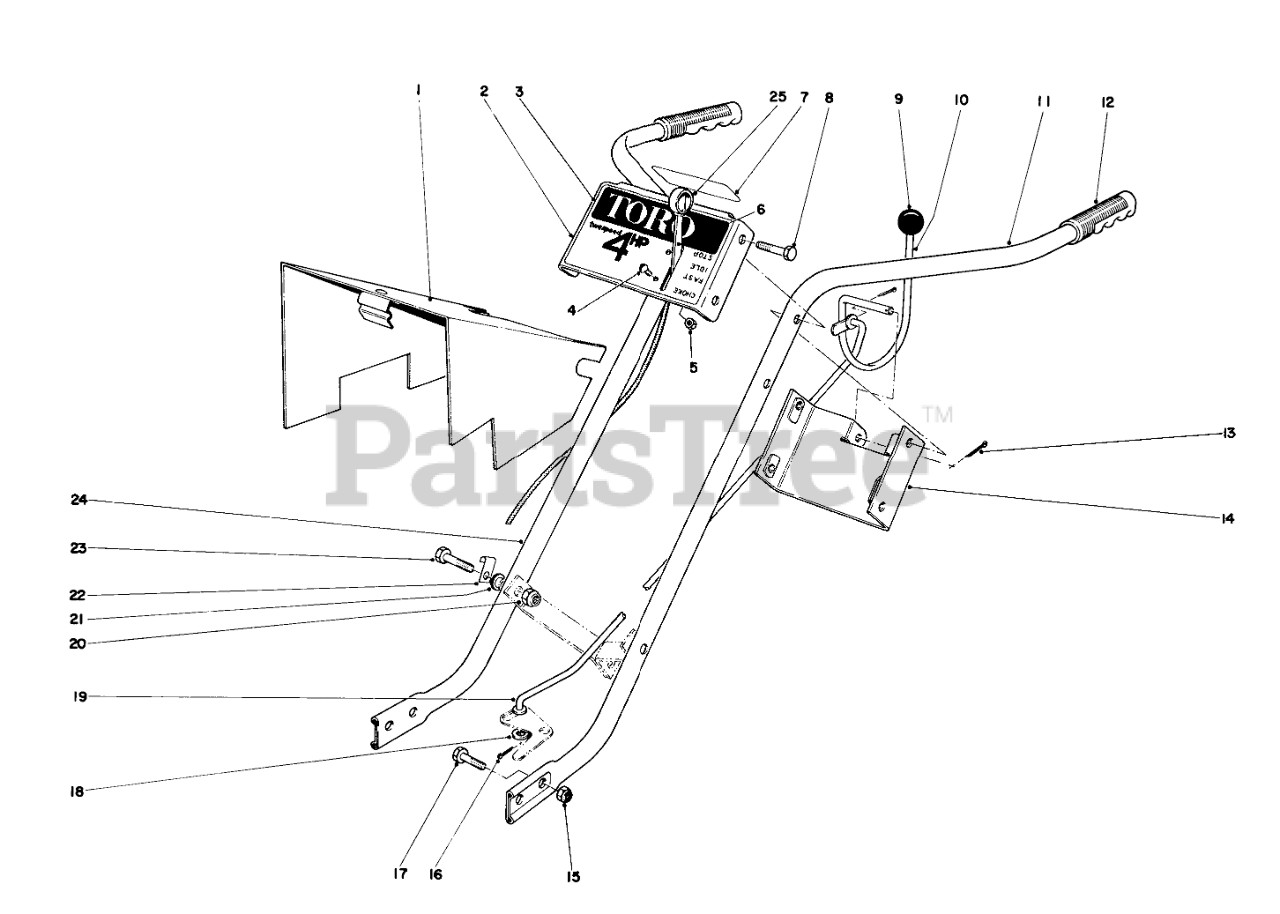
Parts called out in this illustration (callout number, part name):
1	Pulley Cover
2	Control Plate
3	Decal, Control
4	SCREW-PPH
5	NUT-KEPS
6	Throttle Control
7	Decal Clutch
8	SCREW-HH
9	KNOB-CONTROL
10	Clutch Control
11	Handle L.H.
12	Handle Grip
13	PIN-COTTER
14	Handle Brace
15	NUT-LOCK, CONE
16	PIN-COTTER
17	SCREW-HH
18	WASHER-FLAT
19	Clutch Rod
20	NUT-LOCK, CONE
21	Spacer
23	SCREW-HH
24	Handle R.H.
